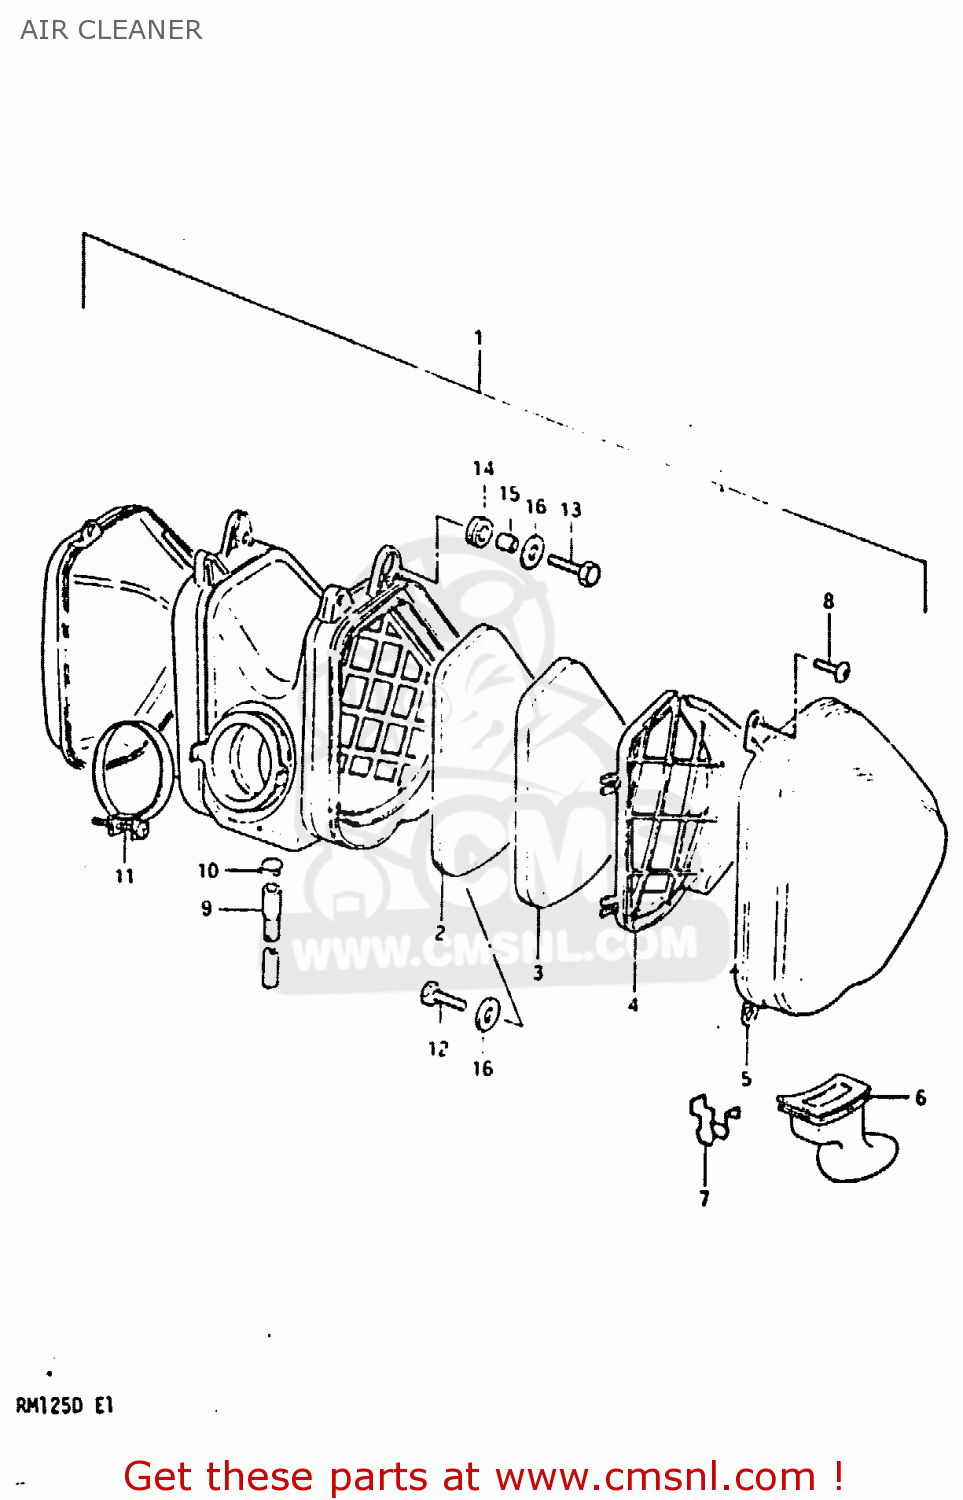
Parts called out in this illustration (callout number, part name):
1	CLEANER ASSEMBLY,AIR
2	FILTER,L
3	FILTER,2ND,R
4	HOLDER,AIR CLEANER ELEMENT
5	CAP,AIR CLEANER,LEFT
6	DRAIN TUBE,LEFT
7	DRAIN STOPPER
8	SCREW
9	DRAIN TUBE
10	CLIP
11	CLAMP
12	BOLT, UPPER
13	BOLT
14	CUSHION
15	SPACER (7X9X7)
16	WASHER
